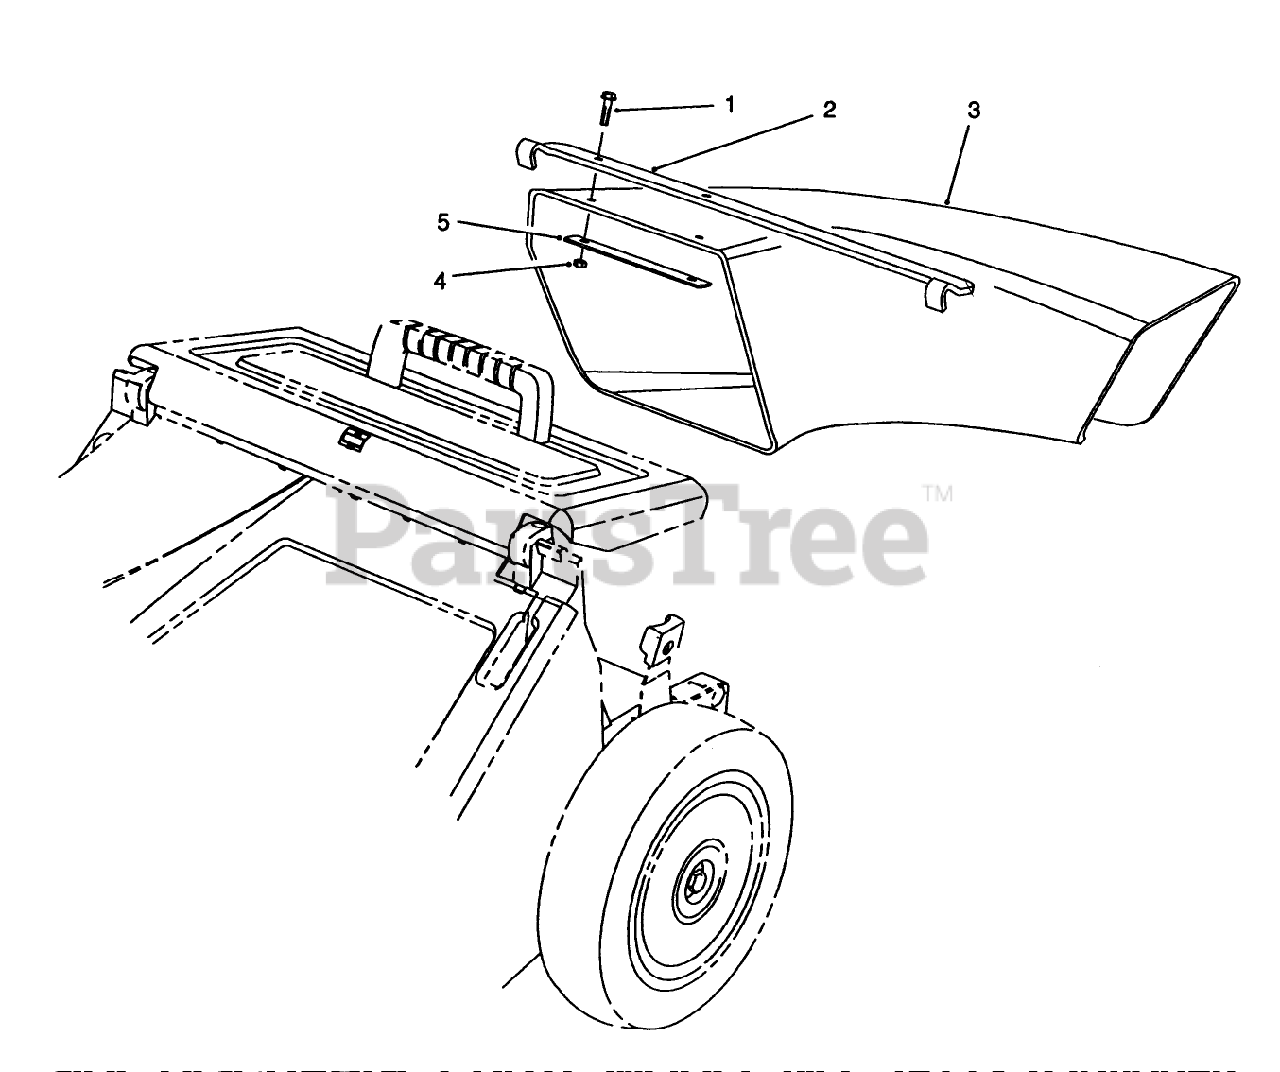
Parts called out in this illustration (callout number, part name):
1	SCREW-HWH
2	CHUTE HANGER BRACKET*
4	NUT-LOCK, NI
